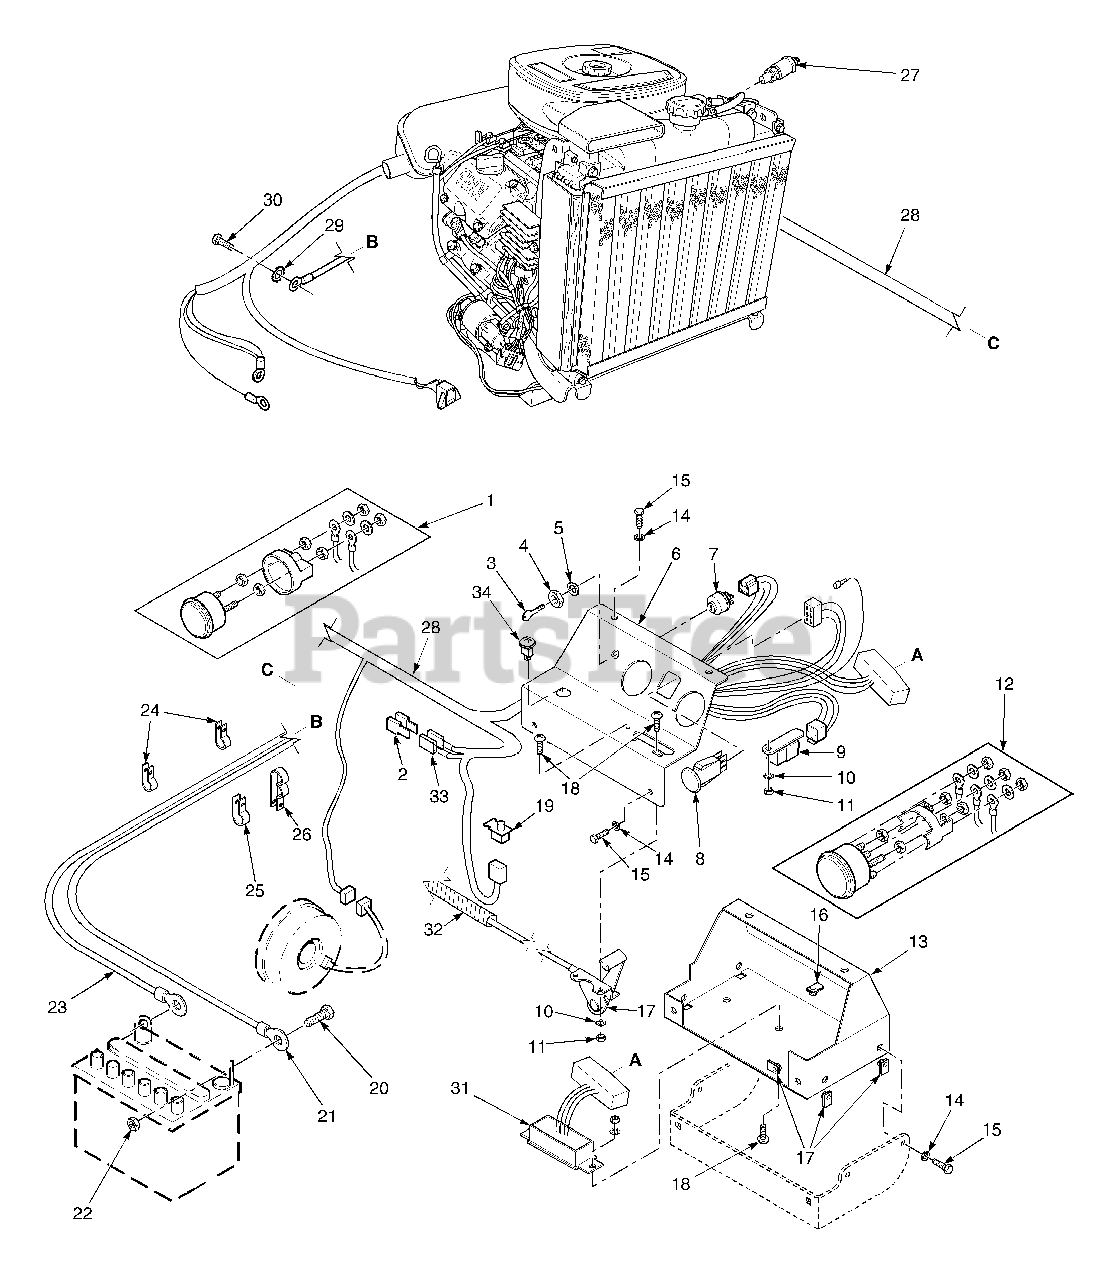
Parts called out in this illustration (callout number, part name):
1	Ammeter
2	Fuse, 20 AMP
3	Key & Ring Assembly
4	Nut, Hex 5/8-32
5	Lockwasher, 5/8" Internal
6	Instrument Panel, Top w/Decals
7	Key Switch
8	Switch, PTO
9	Relay
10	Lockwasher, #10 External Tooth
11	Nut, Hex #10-32
12	Water Temp. Gauge (STT - KA Only)
13	Base, Instrument Panel
14	Lockwasher, 1/4"
15	Bolt, Hex Head 1/4-20 x 3/4"
16	U-Nut, 1/4-20
17	Throttle Controls
18	Screw, Phillips Washer Head #10-32 x 1/2"
19	Switch, Interlock-Seat
20	Bolt, Hex Head 1/4-20 x 1/2"
21	Cable, Battery - Red
22	Nut, Hex 1/4-20
23	Cable, Battery - Black
24	Clamp, Cable 1/2" ID.
25	Clamp, Cable 3/4" ID.
26	Clamp, Cable
27	Sending Unit, Water Temp.
28	Wire Harness, STT Liquid Cooled Digital Fuel Injection (DFI)
29	Lockwasher, 5/16" External Tooth
30	Bolt, Hex Head M8-1.25 x 20
31	Electronic Module
32	Heatshield, Flexible
33	Fuse Holder w/Fuse and Connector
34	Indicator Light, Check Engine
